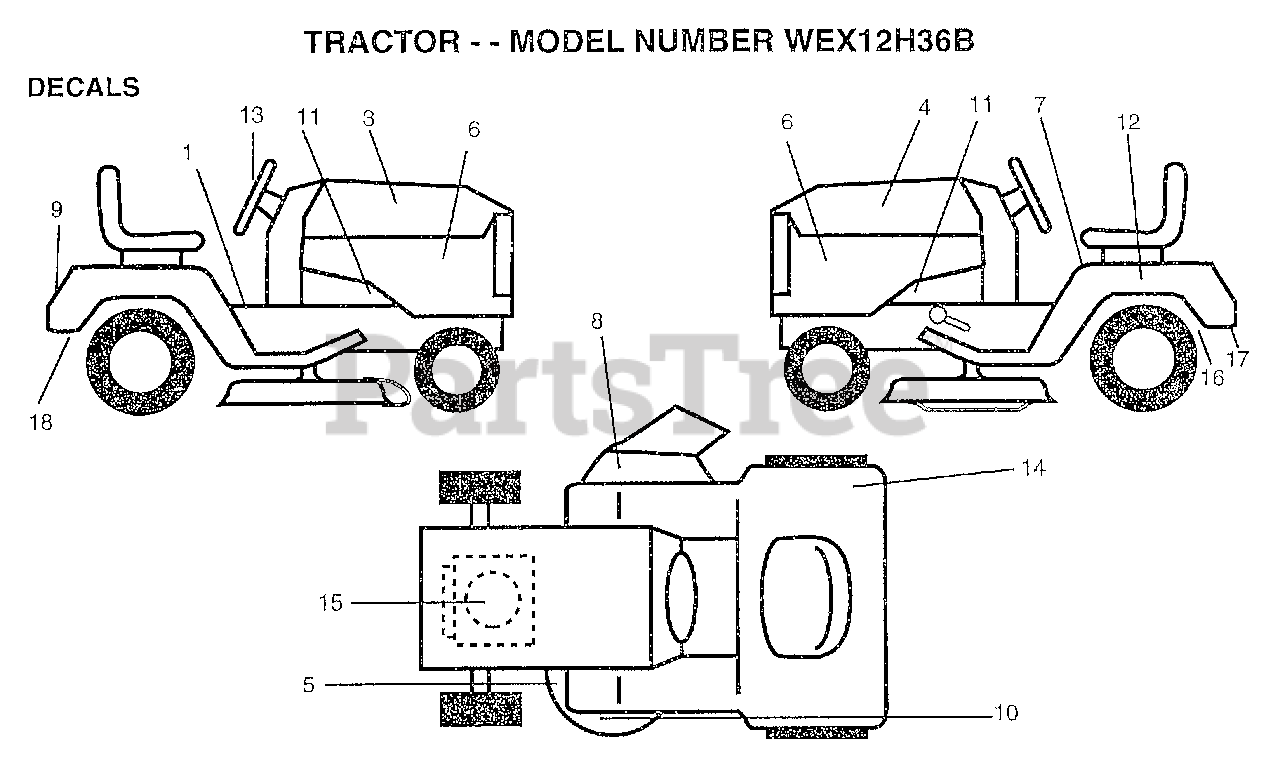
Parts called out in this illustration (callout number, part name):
1	DECAL CLUTCH/BRAK
3	DECAL.HOOD.RH
4	DECAL.HOOD.LH
5	DECAL.V.BELT
6	"DECAL,PNL SIDE"
7	DECAL.READ.O.MANU
8	DECAL.DANGER.CUTF
9	DECAL.FENDER.LOGO
10	DECAL, DECK GRASSEATER
11	"DECAL CHASSIS,HOT"
12	DECAL.BATRY.3-3908
13	DECAL INSRT STEER
16	DECAL.DRAWBAR.LDL
17	DECAL.DRAWBAR.CTL
18	DECAL.EURO.ST.CE.
